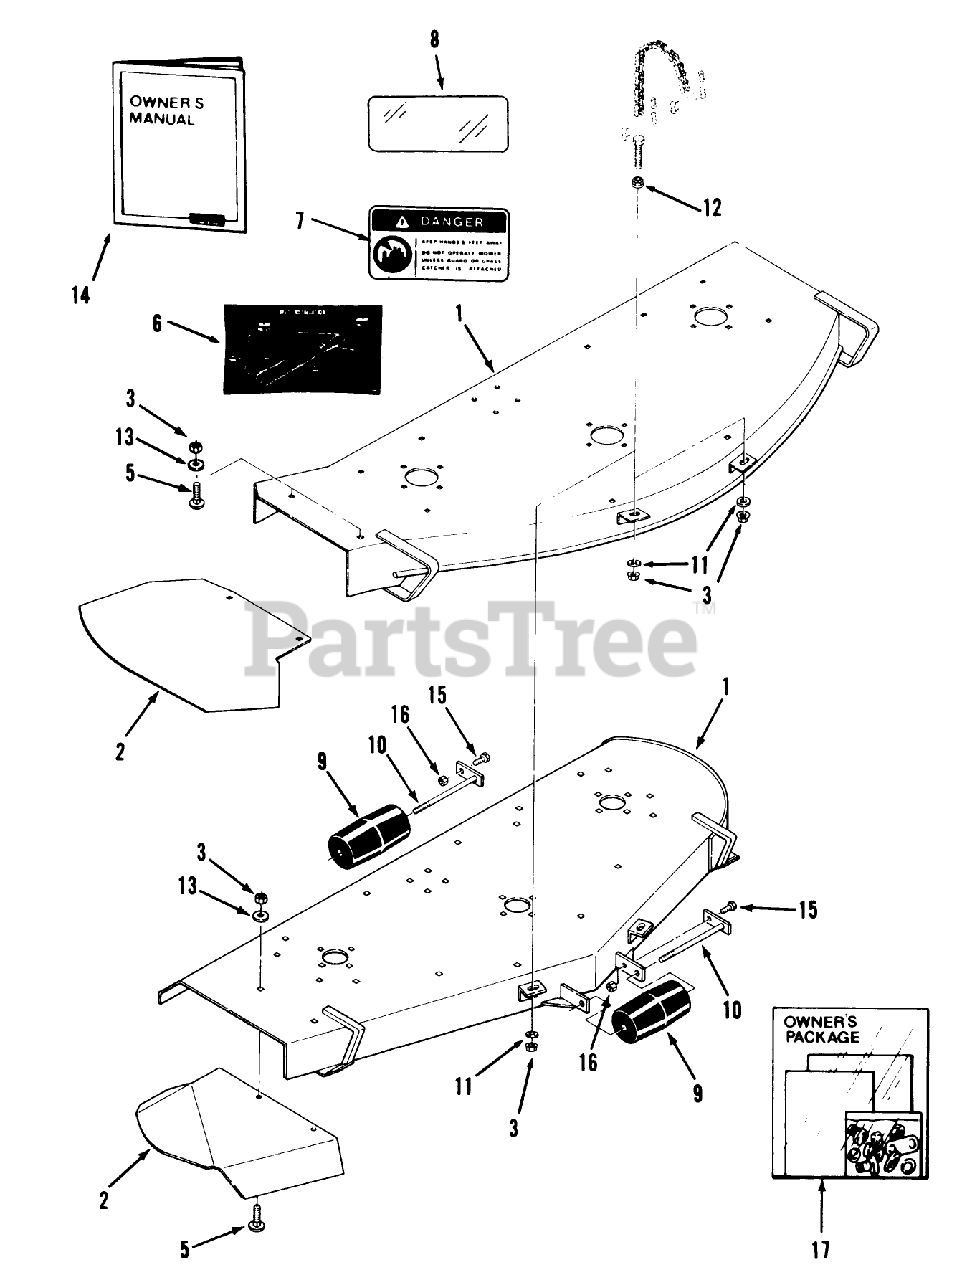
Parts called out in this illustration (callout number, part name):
1	Mower Deck-50" Mower
2	Discharge Chute-50" Mower
3	NUT
5	Bolt-Carriage
6	DECAL-BELT INSTAL
7	Danger Decal
8	DECAL-OVERLAY
9	ROLLER-ANTI SCALP
10	ROLLER-SHAFT
11	Washer
12	NUT
13	WASHER
14	Operating and Maintanence Instructions
15	Bolt
16	Nut
17	Loose Parts Package-50" & 60" Mowers
